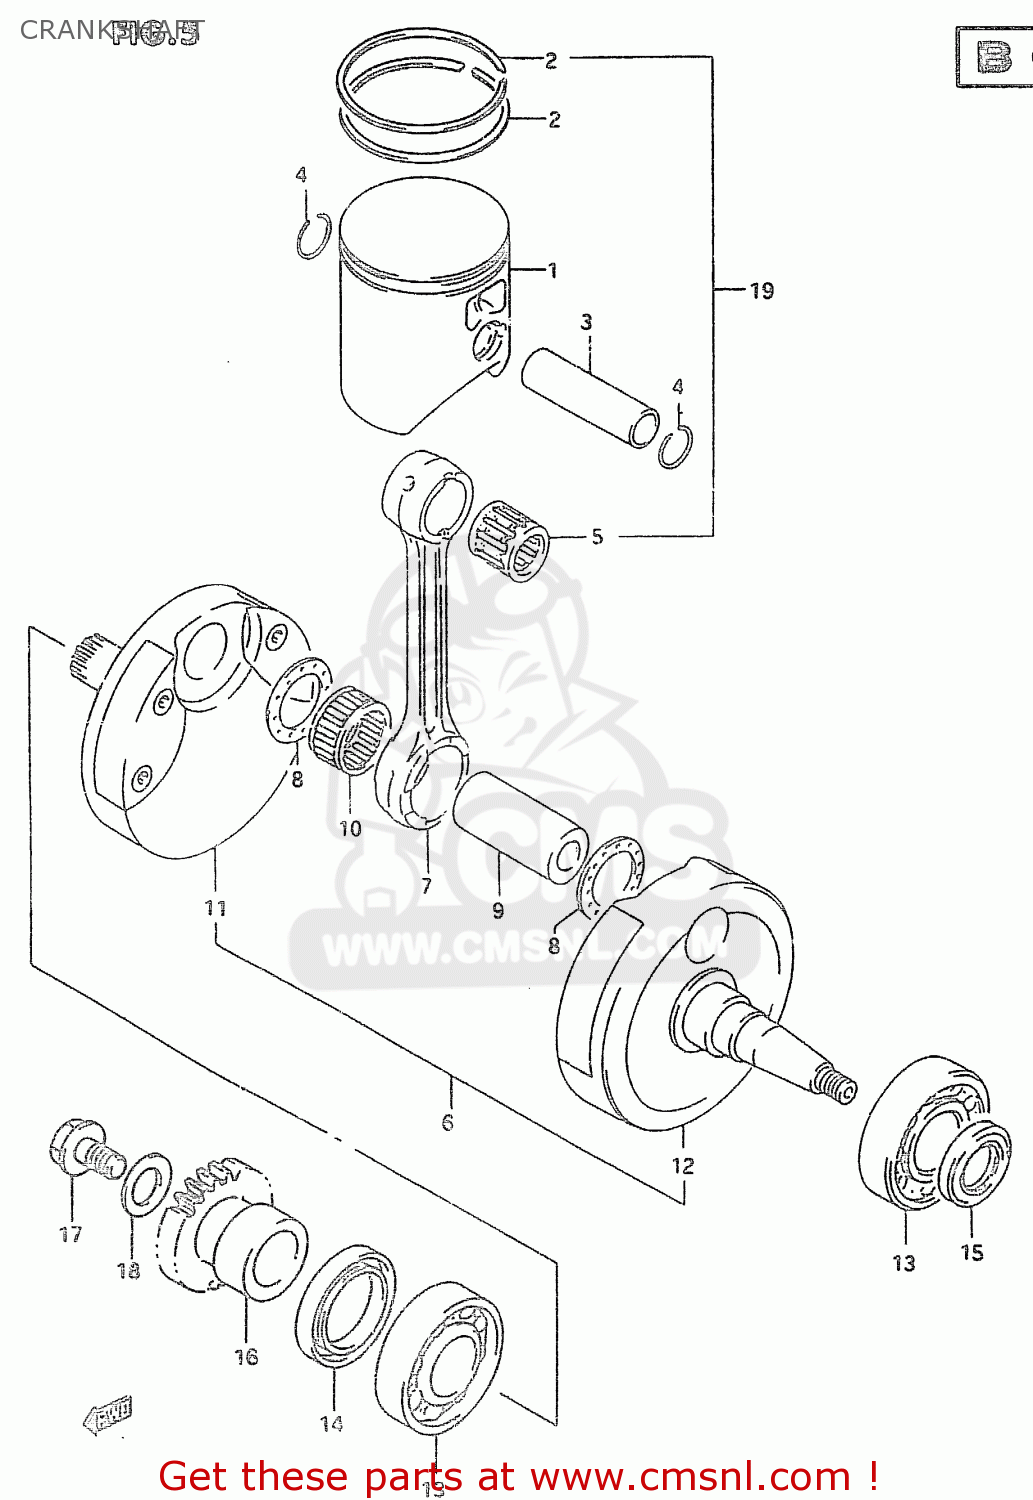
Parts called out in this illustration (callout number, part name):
1	PISTON
2	RING,PISTON
3	PIN,PISTON
4	CIRCLIP,PISTON PIN
5	BEARING(18X23X22)
6	CRANKSHAFT ASSEMBLY
7	CONNECTING ROD
8	WASHER(24X38.5X1.5)
9	PIN,CRANK
10	BEARING(24X30X20)
11	CRANKSHAFT,R
12	CRANKSHAFT,L
13	BEARING(28X68X18)
14	SEAL,OIL(38X52X8)
15	SEAL,OIL(25X37X6)
16	GEAR,PRIMARY DRIVE (NT:
17	BOLT,PRIMARY DRIVE GEAR
18	WASHER
19	PISTON KIT
